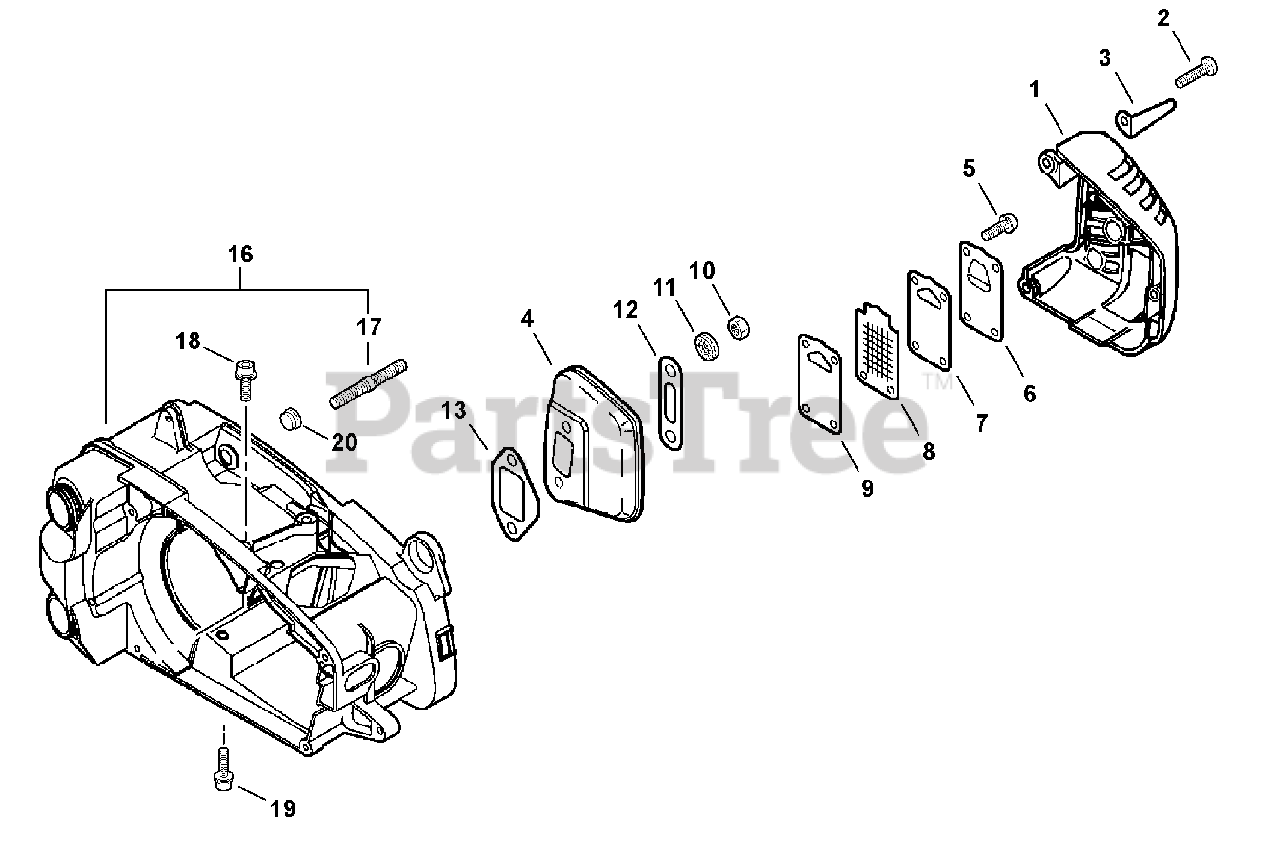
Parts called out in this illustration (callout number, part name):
1	COVER, MUFFLER
2	SCREW 4×16
4	MUFFLER
5	SCREW 4×12
6	OUTLET, EXHAUST
7	GASKET, EXHAUST
8	SCREEN, SPARK ARRESTER
9	GUIDE, EXHAUST
10	NUT M5
12	PLATE, EYE
13	GASKET, EXHAUST
16	COVER ASSY, ENGINE
17	BOLT, STUD 6
18	BOLT 5×20
19	BOLT 5×30
